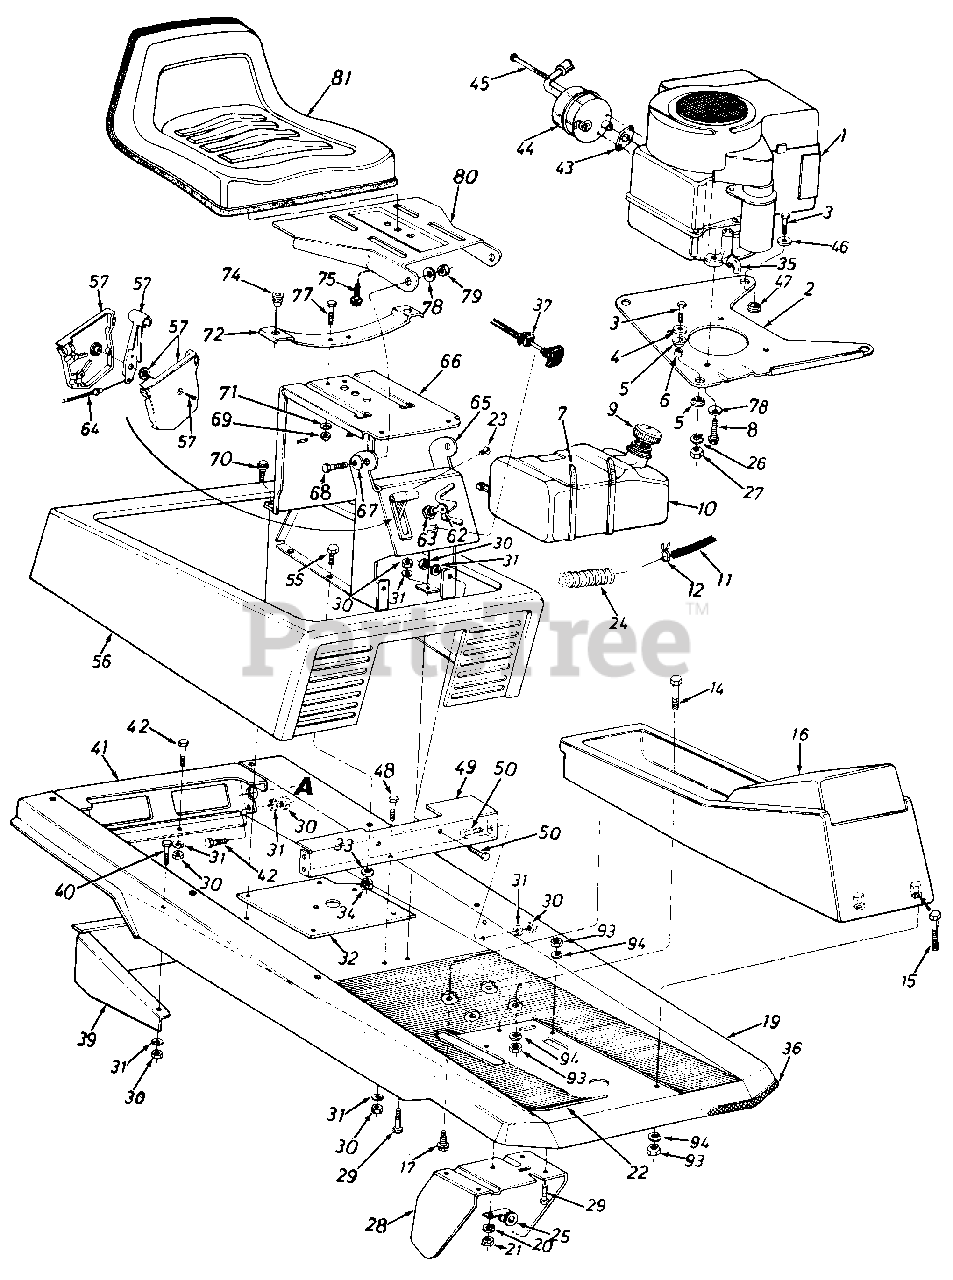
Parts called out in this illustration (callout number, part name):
1	Engine
4	FI-Wash. .330" I.D. x 1.125" 0.D.
5	Engine Mounting Grommet
6	Spacer .315" I.D. x .50" O.D. x .520" Lg.
7	Cable Tie 30.6 Lg.
8	Hex Wash. Hd. Self-Tap Scr. 3/8-16 x 1.25" Lg.
9	Gas Gauge
10	Fuel Tank
12	Hose Clamp-.406" Dia.
14	Hex Bolt 5/16-18 x 1.75" Lg.
15	Hex Bolt 5/16-18 x 2.0" Lg.
16	Front Console
17	Plastite Scr. 5/8 x 1.25"
19	Main Frame
20	L-Wash. 5/16" I.D.
21	Hex Nut 5/16-18 Thd.
23	Truss Mach. AB-Tap Scr. #10 x .50" Lg.
24	Convoluted Conduit
26	L-Wash. 5/16" I.D.
27	Hex Nut 5/16-24 Thd.
28	Clutch-Brake Pedal Ass'y.
29	Hex Bolt 5/16-18 x .75" Lg
30	Hex Nut 5/16-18 Thd.
31	L-Wash. 5/16" I.D.
32	Mounting Brkt. Variable Speed Pulley
33	L-Wash. 1/4" I.D.
34	Hex Nut 1/4-20 Thd.
35	90ø Elbow Male To Female
36	Trim Strip 18" Lg.
37	Choke Control
43	Exhaust Gasket (804)
44	Muffler Ass'y. (804)
45	Shld. Bolt (804)
46	FI-Wash. .330" I.D. x 1.25" 0.D.
47	Flange Wash. .320" I.D. x .750" O.D.
49	Seat Support & Frame Brkt.
50	Hex Bolt 5/16-18 x .75" Lg.
55	Hex Bolt 1/4-20 x .50" Lg.
56	Engine Cover Ass'y.
57	Throttle Control Box Ass'y.
62	Ignition Key
63	Ignition Switch
64	Throttle Control Wire
67	Bell-Wash. .345" I.D. x .88" 0.D.
68	Hex Bolt 5/16-18 x .75" Lg.
69	Hex Nut 5/16-18 Thd.
70	Hex Self-Tap Scr. 5/16-18 x .75" Lg.
71	L-Wash. 5/16" I.D.
72	Seat Spring
75	Hex Wash. Hd. Tap Scr. 3/8-16 x 3/4" Lg.
77	Hex Bolt 1/4-20 x .75" Lg.
78	Bell-Wash. .345" I.D. x .88" 0.D.
79	Hex Cent. L-Nut 5/16-18 Thd.
80	Seat Pivot Bracket
81	Seat Ass'y. Comp.
93	Hex Nut 5/16-18 Thd.
94	L-Wash. 5/16" I.D.
